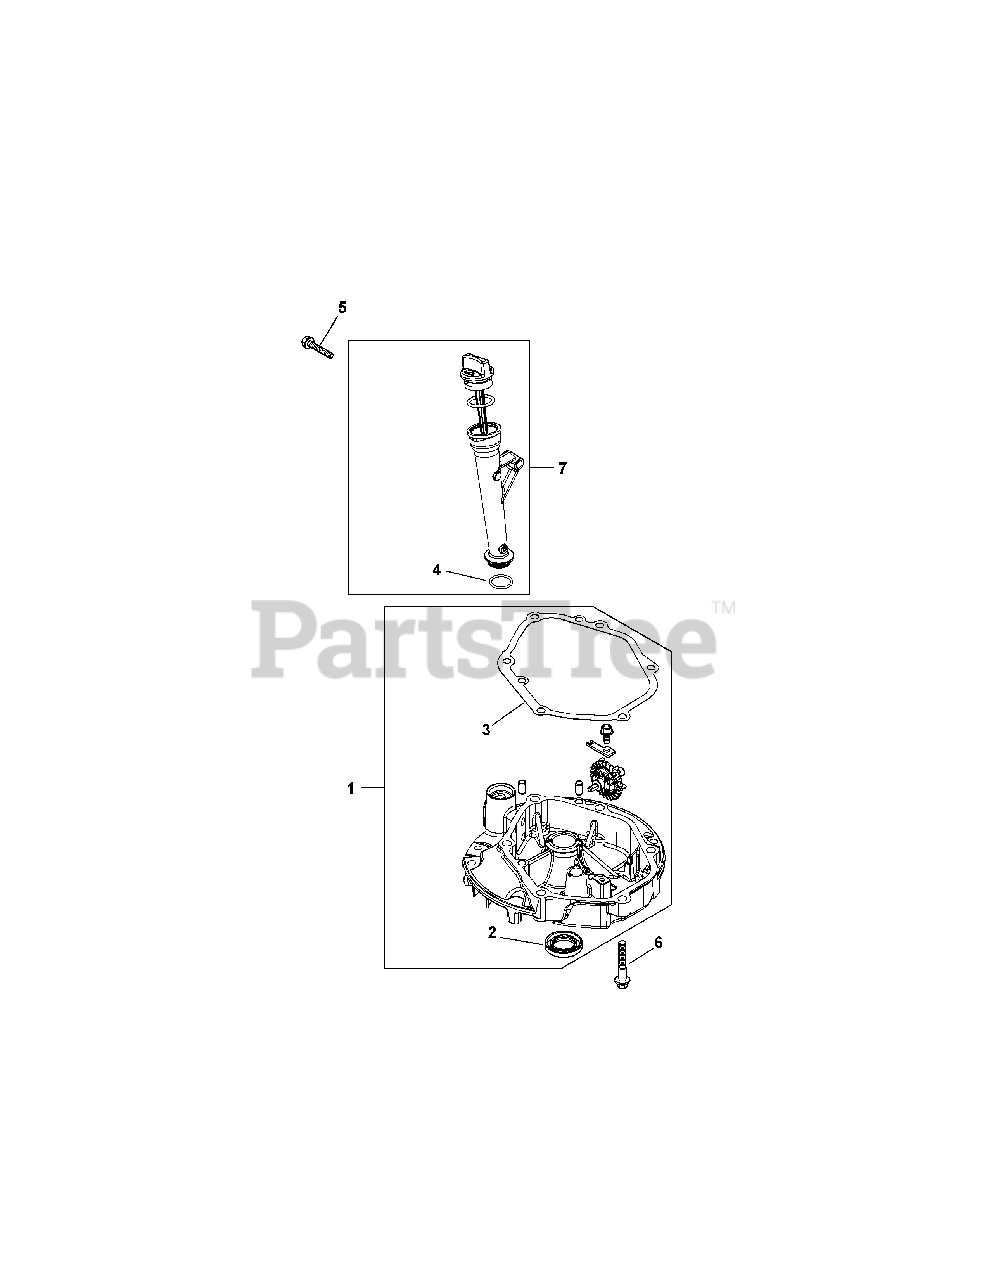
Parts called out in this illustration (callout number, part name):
1	Kit, Oil Pan (Includes 2, 3, Governor Gear Assembly, Dowel Pins)
2	Seal, Oil (PTO)
3	Gasket, Oil Pan
4	O-Ring, Oil Fill Tube
5	Screw, Hex Flange (M6)
6	Screw, Hex Flange (M8)
7	Tube Assembly, Oil Fill (Includes 4)
